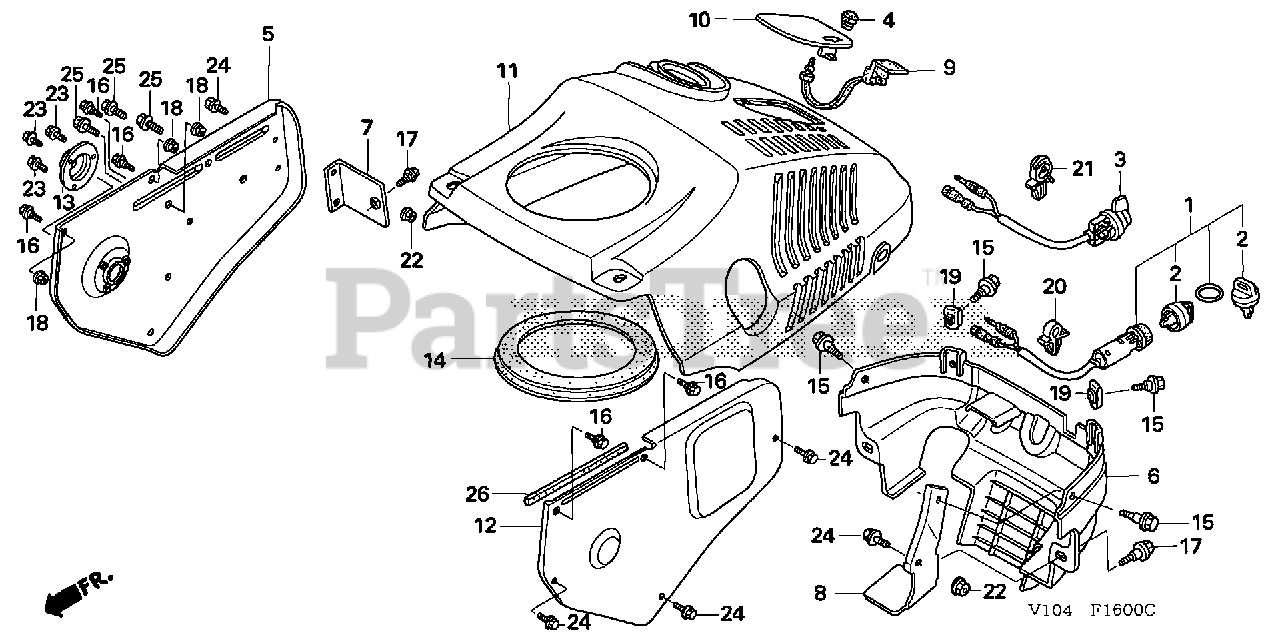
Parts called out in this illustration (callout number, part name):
3	SWITCH ASSY., ENGINE STOP
4	PLUG, HANDLE COVER (LOWER)
5	COVER, R. SIDE
6	COVER, RR.
7	BRACKET, R. RR. COVER
8	BRACKET, L. RR. COVER
9	KNOB, PLUG COVER
10	COVER, PLUG
11	COVER, TOP
12	COVER, BELT
13	HOLDER, R. AUGER (BEARING)
14	RUBBER, CHUTE
15	BOLT, TOP COVER
16	BOLT, SIDE COVER
17	BOLT, RR. COVER
18	NUT, SELF-LOCK (6MM)
19	NUT, AIR SPOILER CLIP
20	CLIP, HARNESS
21	CLIP, WIRE HARNESS
22	NUT, FLANGE (6MM)
23	BOLT, FLANGE (6X10)
24	BOLT, FLANGE (6X12)
25	BOLT, FLANGE (8X16)
26	SEAL KIT, COVER
